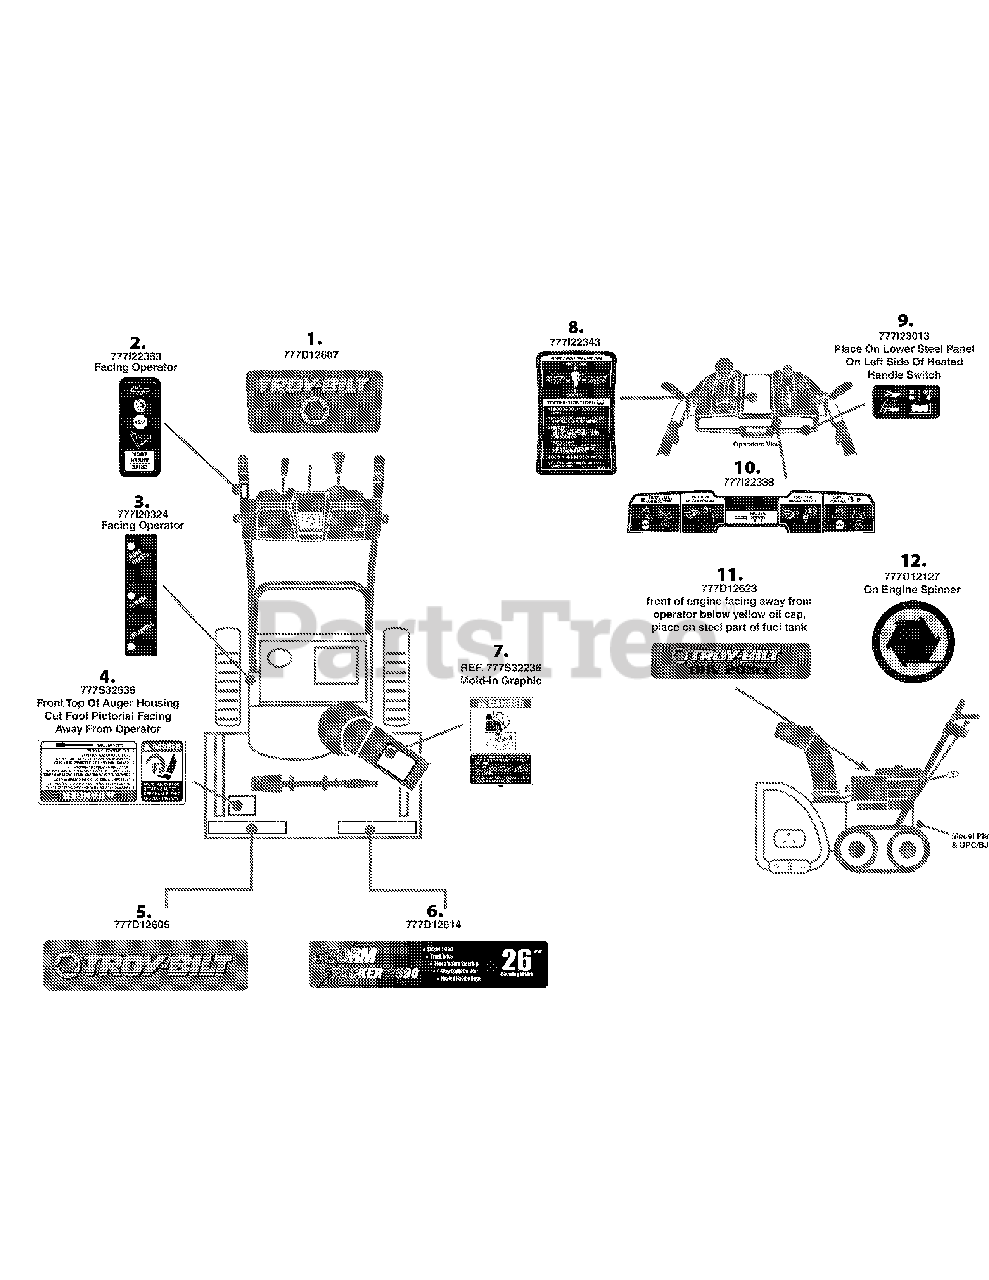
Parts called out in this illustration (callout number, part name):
1	LABEL-SNOW HANDLE 4 STYLE FRONT
2	LABEL-DRV/AUGR LOCK
3	LABEL-TRANSPORT
4	LABEL-SNOW HOUSING
5	LABEL-SNOW FRONT LH AUGER TROY
6	LABEL-SNOW FRONT RH AUGER STORM
7	LABEL-SNOW CHUTE
8	LABEL-HANDLE PNL
9	LABEL-SNOW 2 STAGE HTD HANDLES
10	LABEL-DRIVE CONTRO
11	LABEL-MTD ENGINE TROY
12	LABEL-MTD ENGINE
